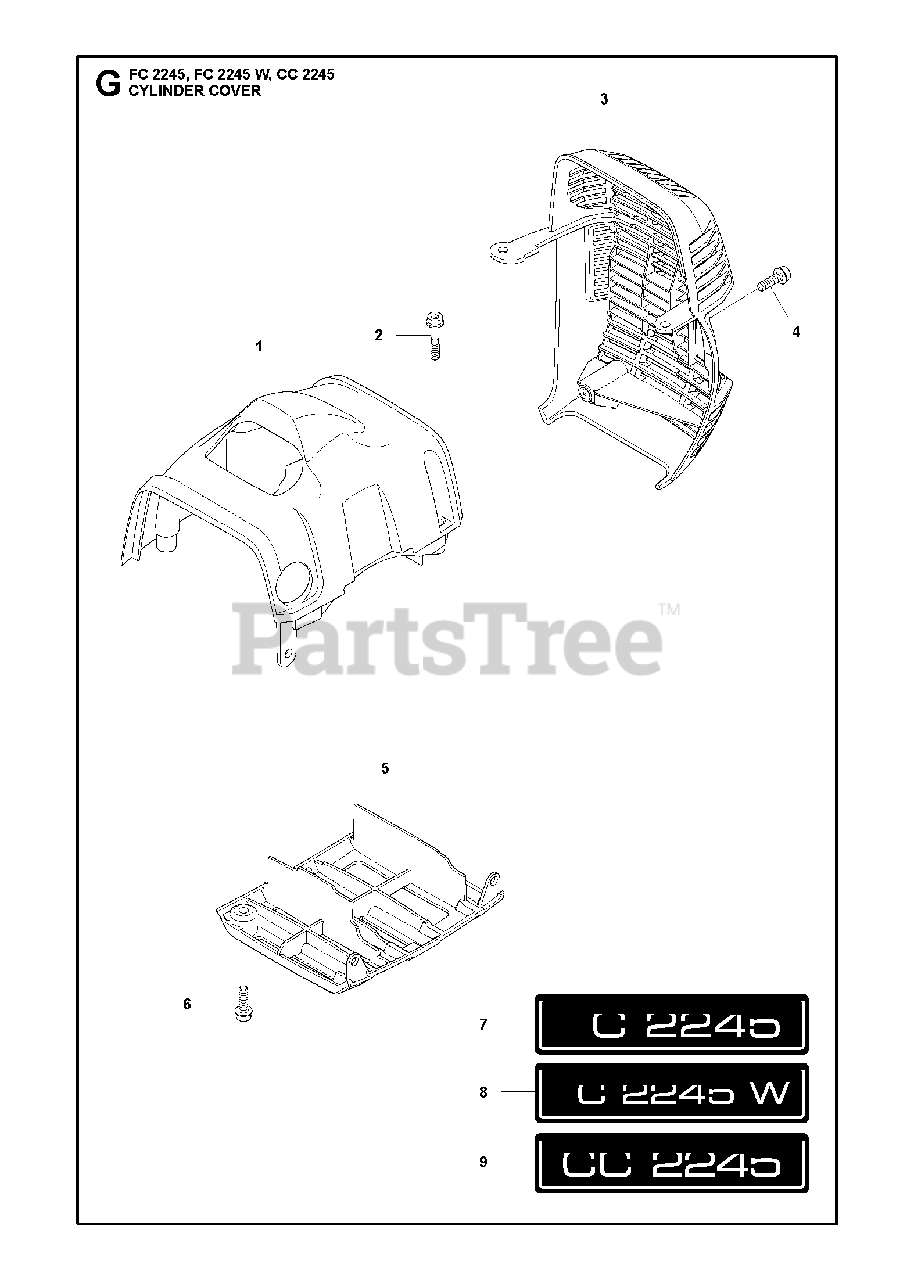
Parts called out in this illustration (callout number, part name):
1	CYLINDER COVER
2	SCREW IHSCFMO
3	HEAT PROTECTOR
4	SCREW IHSCFM
6	SCREW IHSCFM
9	DECAL
